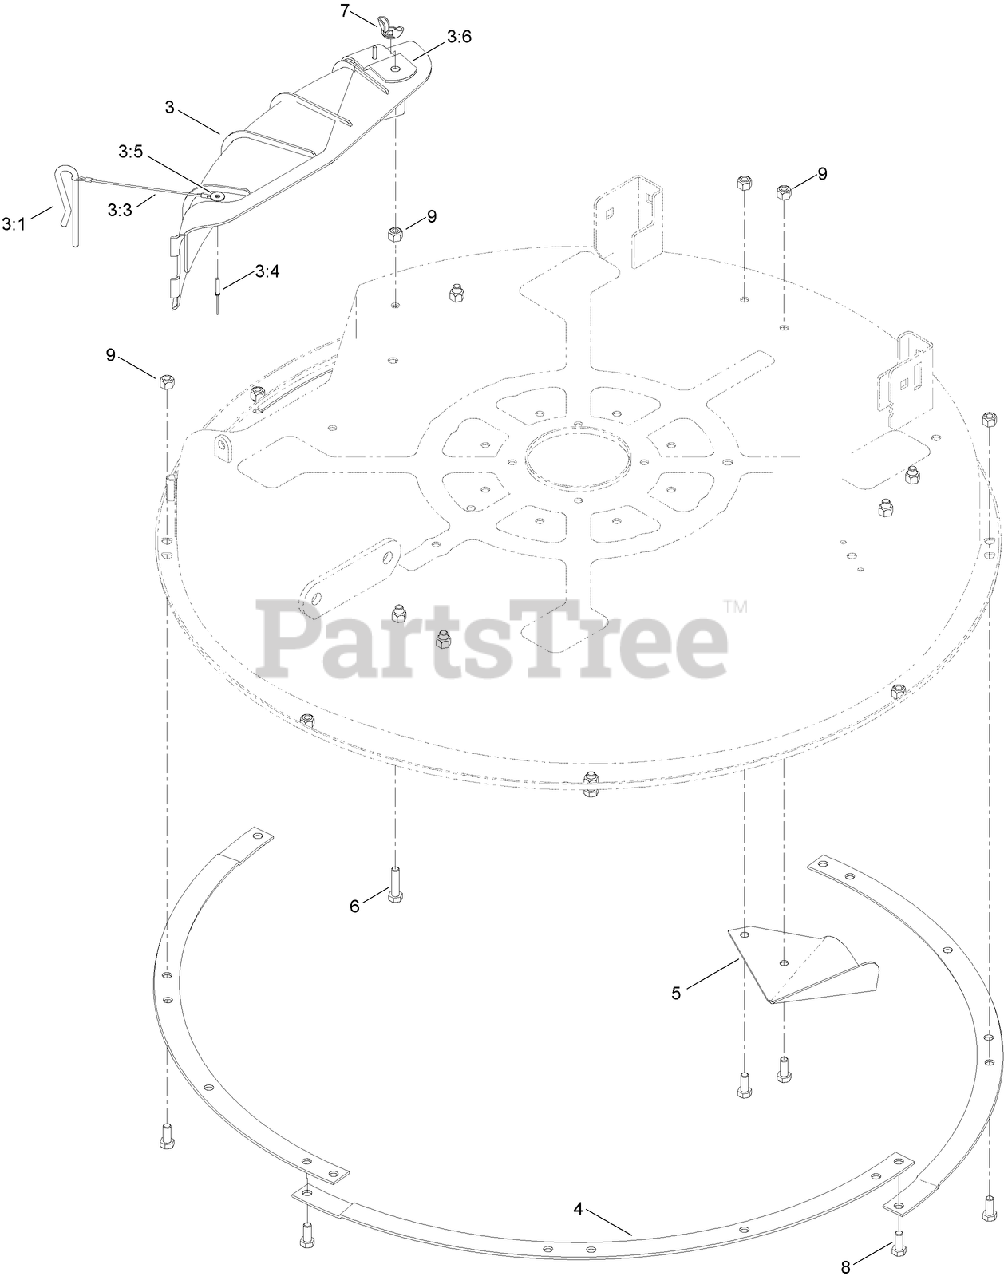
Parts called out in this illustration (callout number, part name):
3	DISCHARGE COVER ASM
3:1	PIN-LOCKING, CHUTE
3:3	LANYARD
3:4	RIVET-BLIND
3:5	WASHER-PLAIN
4	RING-DECK
6	SCREW-HH
7	NUT-WING
8	SCREW-HH
9	NUT-LOCK, NI
